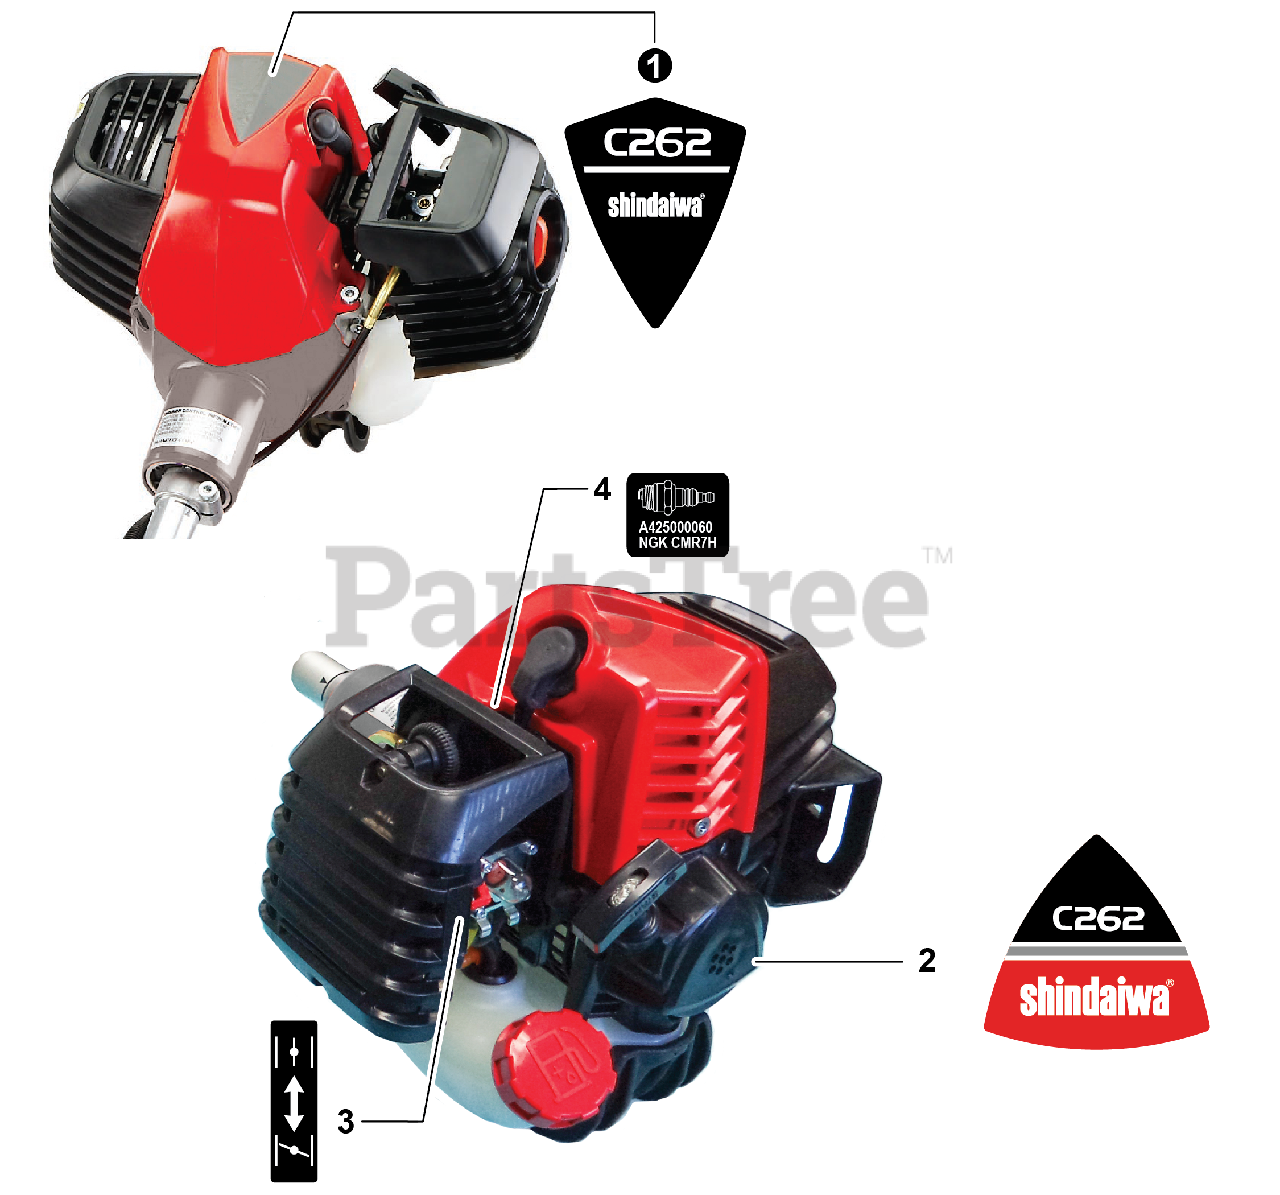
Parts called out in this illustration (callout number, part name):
1	LABEL - MODEL C262
2	LABEL, RECOIL STARTER
3	LABEL, CHOKE
4	LABEL, SPARK PLUG - CMR7H
